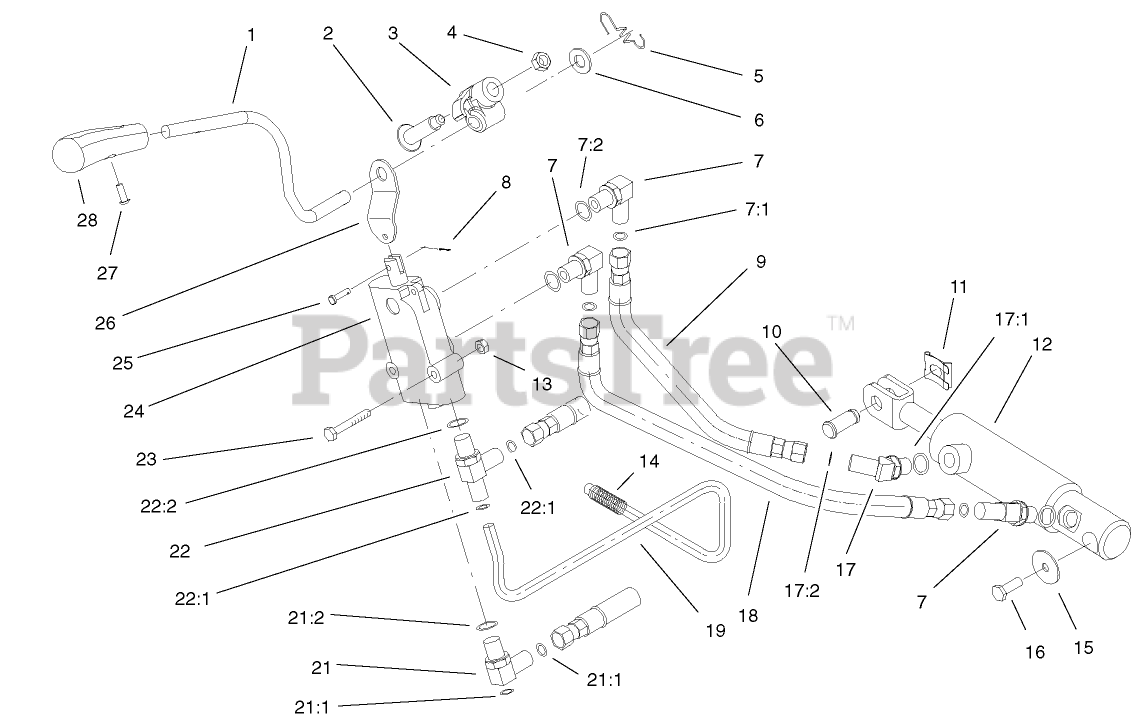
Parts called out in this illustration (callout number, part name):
1	HANDLE-LIFT
2	BOLT-SHOULDER
3	TRUNNION-LEVER, LIFT
4	NUT-JAM, LOCKING
5	SPRING-EXTENSION, LIFT
6	WASHER
7:1	O-RING
7:2	O-RING
8	PIN-COTTER
9	HOSE ASM
10	PIN-CLEVIS
11	CLIP-PIN
12	LIFT CYLINDER ASM
13	NUT-LOCK, NI
14	COVER-BRACE
15	WASHER-FLAT
16	SCREW-THREAD LOCKING
17:1	O-RING
17:2	O-RING
18	HOSE ASM
19	TUBE-HYD
21:1	O-RING
21:2	O-RING
22	FITTING-TEE
22:1	O-RING
22:2	O-RING
23	SCREW-HH
24	VALVE-HYD
25	PIN-CLEVIS
26	LINK-LIFT
27	SCREW-PPHTF
28	KNOB-LIFT
28	KNOB - LIFT
